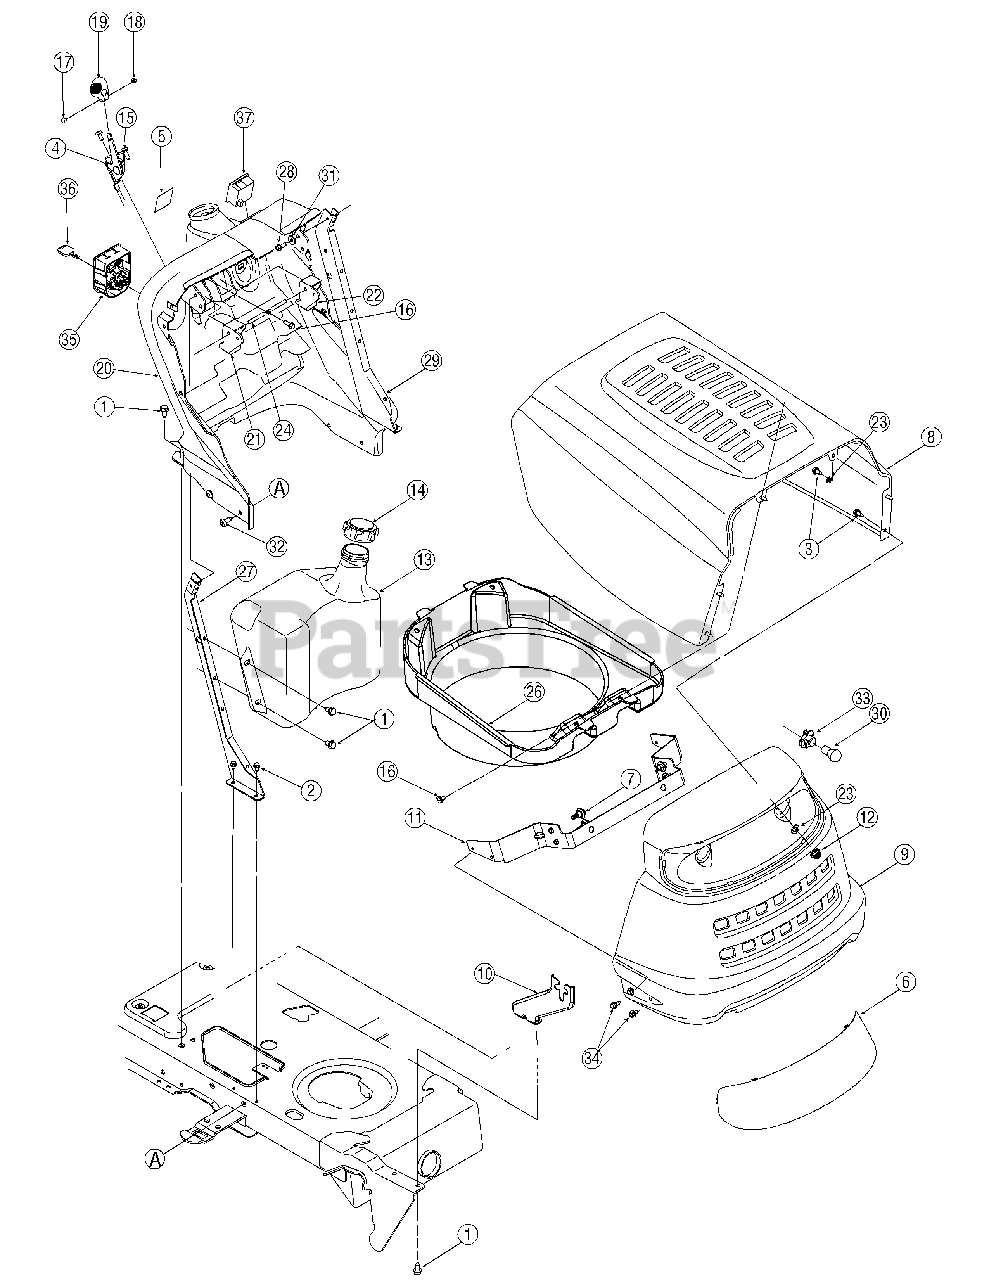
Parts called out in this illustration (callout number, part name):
1	Screw, 5/16-12 x.750
2	Self-tapping Screw, 1/4-20 x.5
3	Hex Cap Screw, 1/4-20 x.62
4	Throttle Control/Cable
5	Choke Plug
6	Headlight Lens
7	Shoulder Screw,.43 x.29
13	Fuel Tank, Two Gallon
14	Fuel Cap
15	Screw, 1/4-14 x.625
16	Self-tapping Screw, 1/4-15 x.75
17	Truss Phillips Screw, #8-32 x.375
18	Hex Nut, #8-32
19	Throttle Control Knob
20	Dash Panel
21	Cruise Control Button
22	Parking Brake Button
23	Flat Washer, .265 x .938 x 1.20
24	Brake/Cruise Pivot Rod
26	Hood Plenum
30	Lamp
31	Bell Washer,.265 x.75 x.062
32	Screw, 5/16-18 x.75
33	Headlight Socket
34	Hex Index Screw, 1/4-20 x.625
35	Ignition Switch
36	Ignition Key w/ plastic cover
36	Ignition Key w/o plastic cover
37	Systems Ind. Monitor w/ Hr. Meter (if equipped)
37	Systems Ind. Monitor w/ Ammeter
37	Wire Harness (w/Hour Meter) (if equipped)
